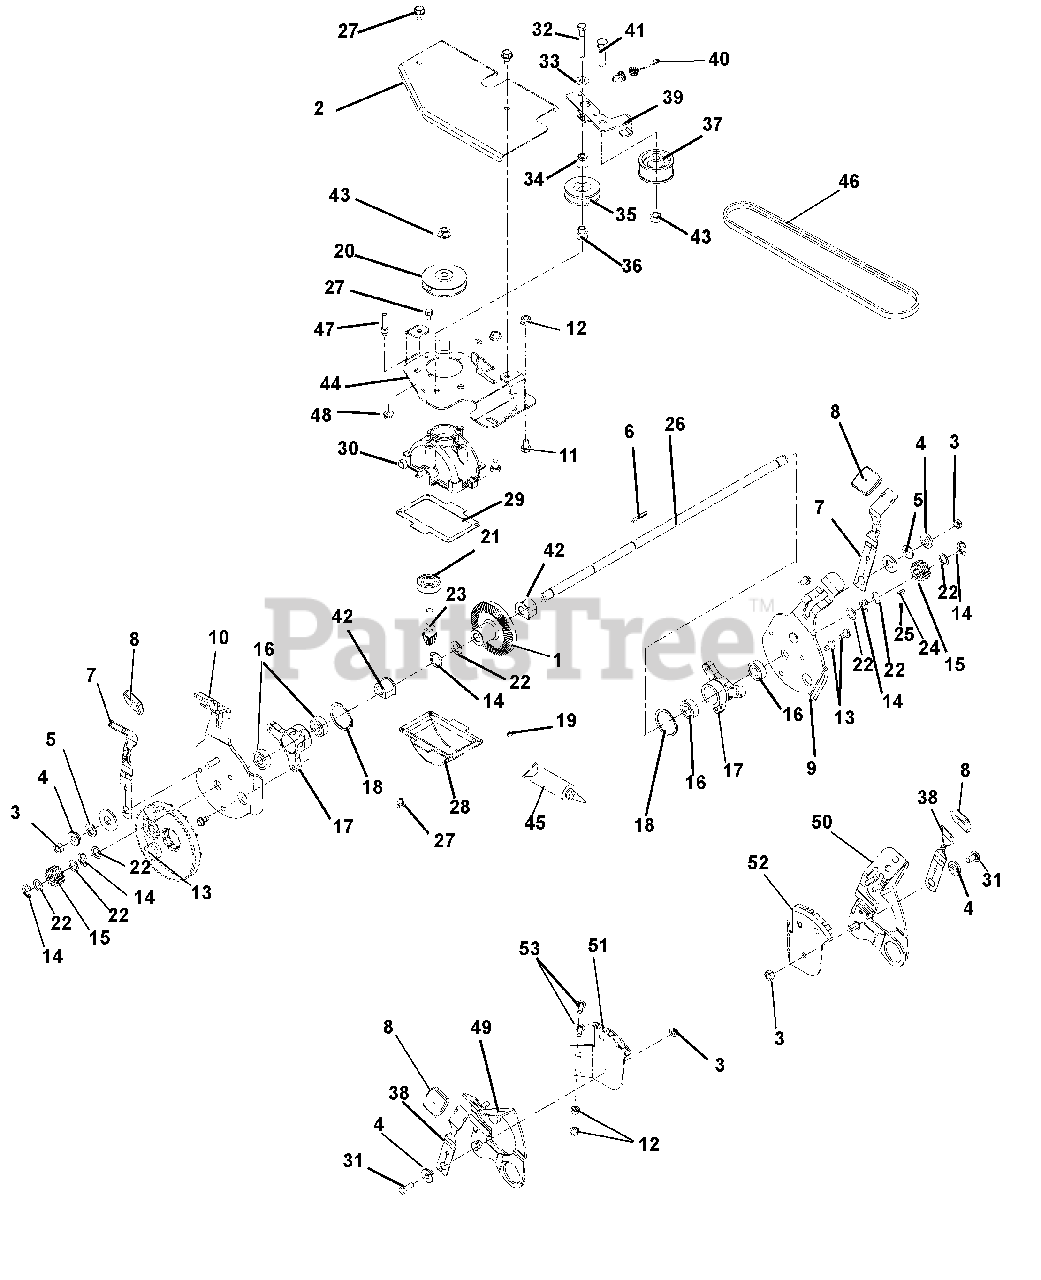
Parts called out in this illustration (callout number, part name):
1	Gear, Reduction
2	Cover, Transmission
3	Nut, Locking-Center .31-18
4	Bushing, Flange .265 x .437 x .250 x .750
5	Washer, Flat-Steel .52 x .827 x .062
6	Key, 1/8 x 1/8 x 1.0
7	Lever, Height Adjustment
9	Weldment, Height Adjuster RHS
10	Weldment, Height Adjuster LHS
11	Bolt, Hex .31-18 x .50 Grade 5
12	Nut, Locking-Top-Flange .31-18
13	Screw, Tapping .25-20 x .50 Hex Washer Head
14	Ring, Retaining-Internal .50 x .049
15	Pinion, WBLM Drive
16	Bearing, .375 x .875 x .281
17	Bushing, Height Adjuster Pivot
18	Ring, Retaining External 1.387 x .050
19	Fitting, Lube .25-28 x .256
20	Half, Transmission Input Pulley
21	Bearing, Ball .625 x 1.375 x .43
22	Washer, .500 x .750 x .020 Thrust
23	Pinion, Gearbox Input
24	Key, Woodruff .125 x .50 x .20
25	Spring, .134 x .186 x .144 Compression
26	Shaft, Transmission Output
27	Screw, Tapping 10-24 x .375 Hex Washer Head
28	Sump, Gearbox
29	Gasket, Transmission
30	Casting, WBLM Gear Box
31	Bolt, Hex .31-18 x 1.00 Grade 5
32	Bolt, Hex .25-20 x 2.25 Grade 8
33	Washer, Flat Steel .328 x 1.0 x .094
34	Spacer, .390 x .75 x .189
35	Idler, 3L Front Side .38 x 1.875
36	Spacer, Idler Pulley
37	Idler, Flat 1.875OD x .75 Wide
38	Front Height Adjustment Lever
39	Arm, Transmission Idler
40	Spring, Tension .051 x .60 x 2.25
41	Bolt, Hex .38-16 x 1.25 Grade 5
42	Bushing, Transmission Output Shaft
43	Nut, Locking-Top-Flange .38-16
44	Bracket, Transmission Control
45	Lubricate
46	V-Belt 3L 35.98
47	Finger, Belt
48	Nut, Locking-Flange .250-20
49	Right Hand Adjuster Bracket
50	Left Hand Adjuster Bracket
51	Front Quadrant, Right Hand
52	Front Quadrant, Left Hand
53	Bolt, Round Head Square Neck .31-18 x 1.00 G5
